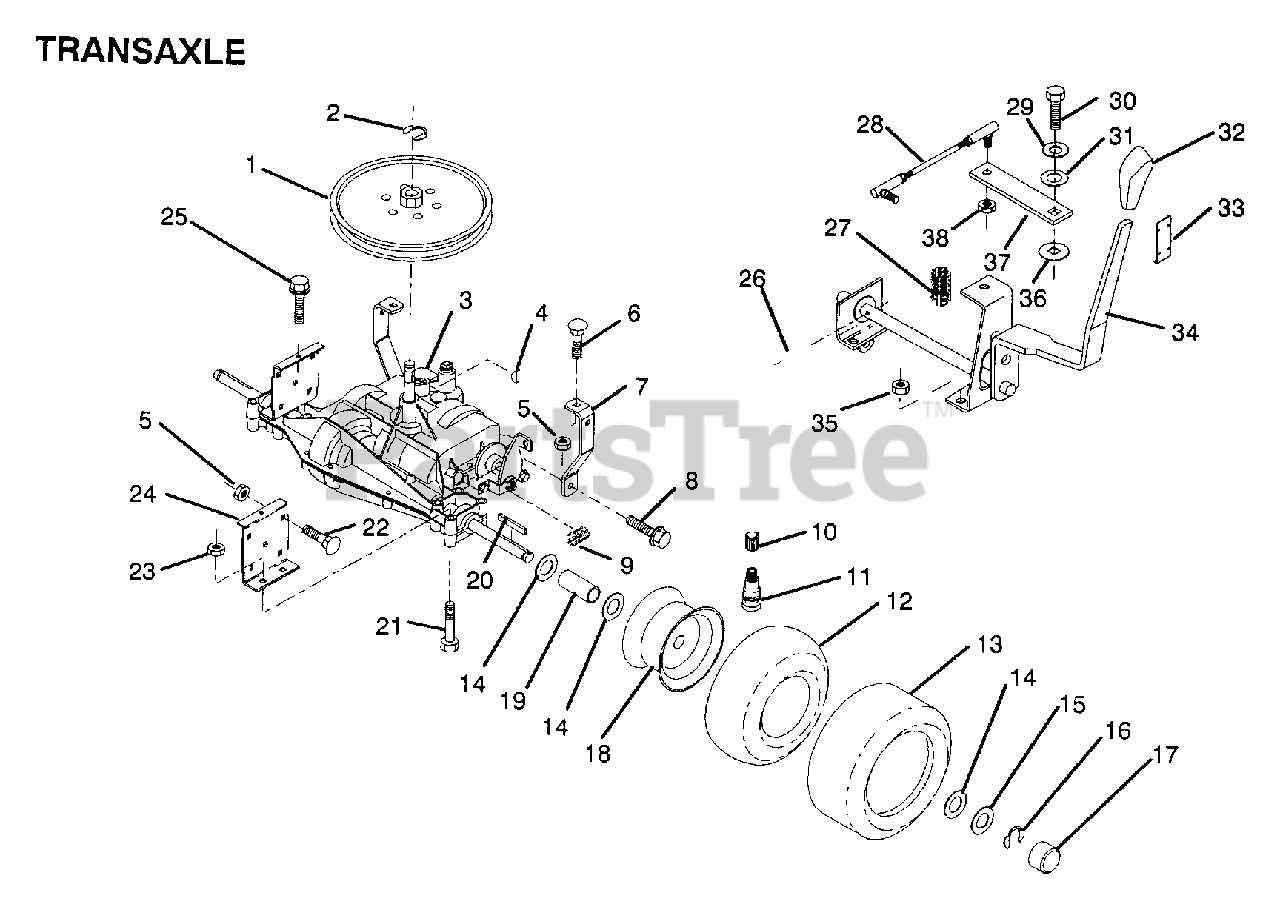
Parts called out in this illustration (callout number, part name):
1	PULLEY
6	BOLT
7	"STRAP,TORQUE"
8	SCREW LT
10	VALVE CAP
11	VALVE STEM LT
12	TUBE.16X6.5/7.5-8
14	WASHER
15	WASHER
16	E-RING LT
17	HUB CAP
19	SPACER
20	SQUARE KEY
21	BOLT
22	BOLT
24	"BRKT,TRANSAXLE"
25	SCREW
26	PIN COTTER 1/8
27	EXT SPRING
28	"LINK,SHIFT"
29	LOCKWASHER
31	WASHER LT
32	"KNOB,SHT CONTROL"
33	KNOB RETAINER
34	SHIFT HANDLE ASSY
36	WASH-SHFT PLT LT
37	"ARM,SHIFT"
38	NUT.LOCK.5/16-24
